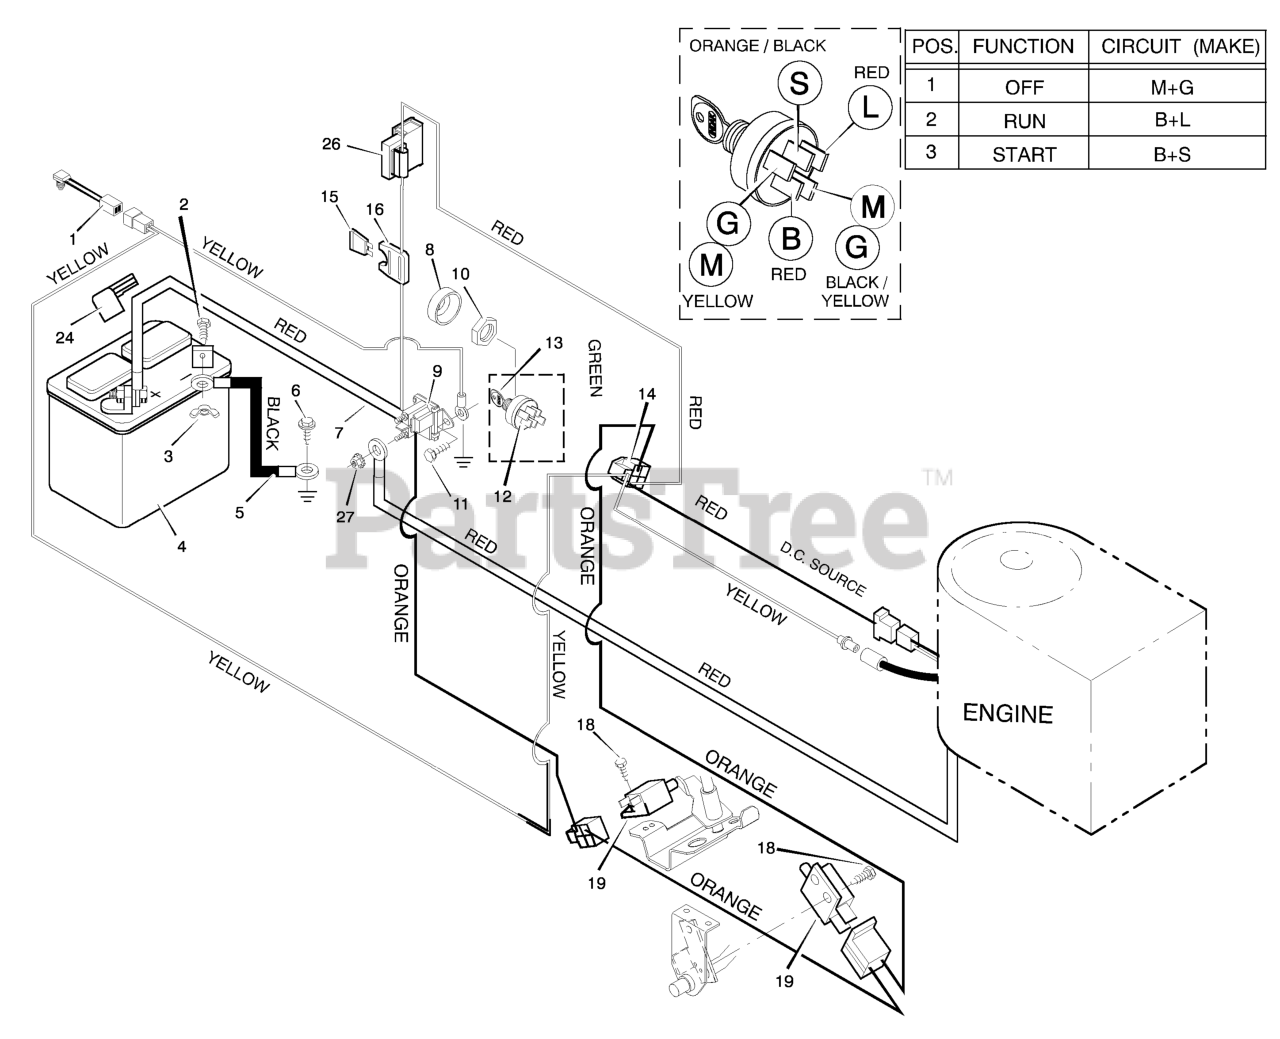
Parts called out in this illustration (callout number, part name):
1	Switch, Seat Sensor
2	Bolt
3	Wingnut
4	Battery
5	Cable, Battery Ground
7	Cable, Red Battery
8	Cap, Ignition
9	Solenoid
10	Nut
12	Switch, Ignition
13	Key, Ignition
14	Harness, Chassis Wire
16	Holder, Fuse
19	Switch, Clutch
24	Cover, Terminal
27	Locknut
